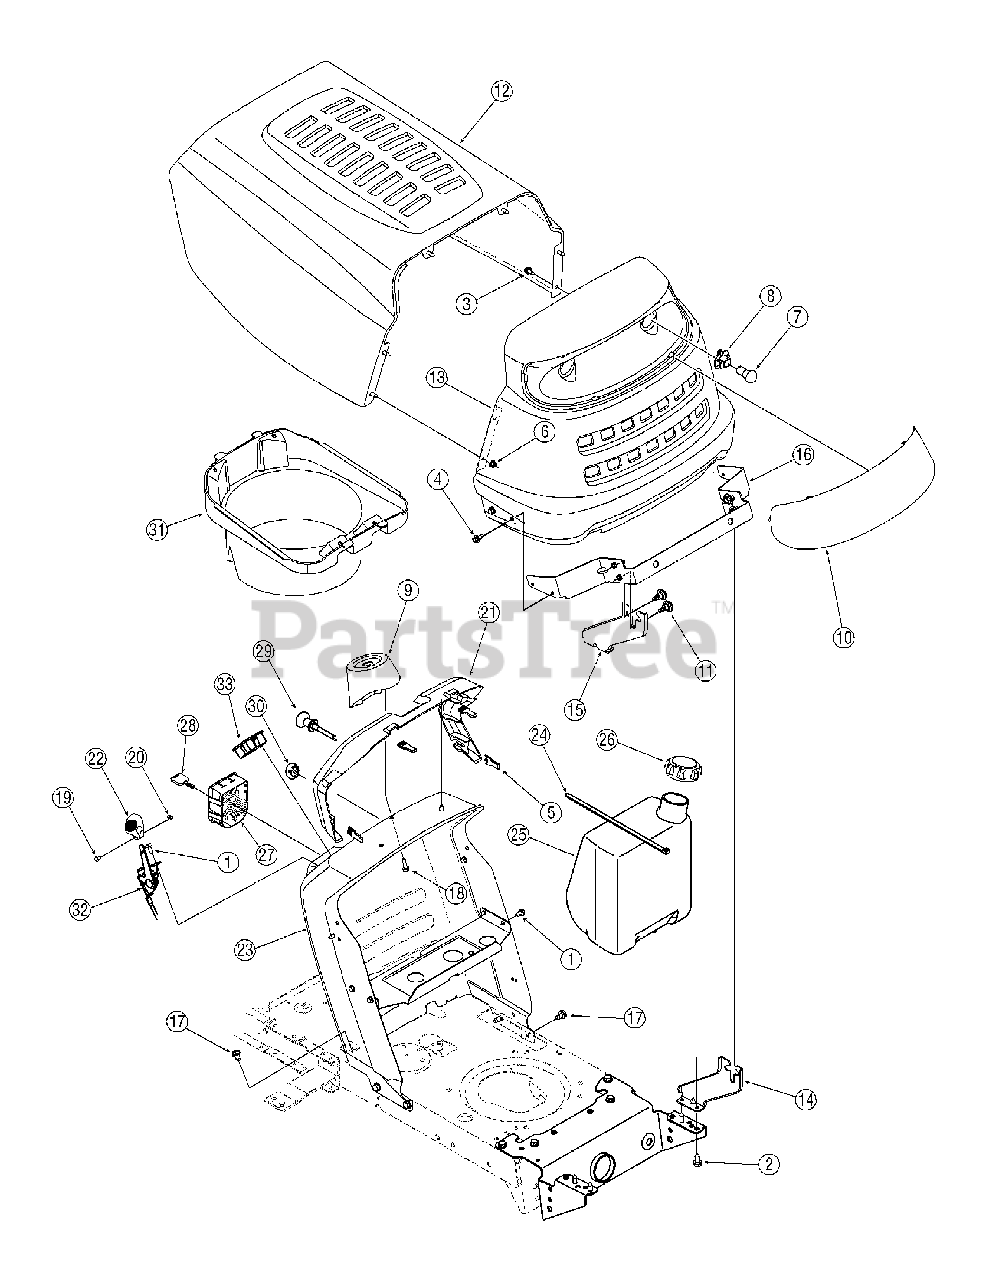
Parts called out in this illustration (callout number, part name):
1	Screw, 1/4-20, 0.500
2	Screw, 5/16-12, 0.750
3	Screw, 1/4-20, .620, Gr5
4	Screw, 1/4-20, .625
5	Nut, 1/4-20, Speed U-type
6	Nut, Flange Lock, 1/4-20, GrF, Nylon
7	Headlamp, 12V
8	Headlamp Socket
9	Collar, Dash
11	Screw, Shoulder, .43 x.29, 5/16-18
15	Pivot Bracket, RH
16	Pivot Bracket, Grille
17	Screw, 5/16-18, 0.500
18	Screw, 1/4-15, 0.750
19	Screw, Machine, #8-32, 0.375
20	Nut, Hex, #8-32, GrA
21	Support, Steering
22	Knob, Control
23	Dash Assembly (Models w/o Ammeter)
25	Fuel Tank, 1.5 gal.
26	Fuel Tank Cap
27	Module, Ignition Switch
29	Choke Control, 37.5"
31	Plenum (Single Cylinder Engine)
31	Plenum (Twin Cylinder Engine)
32	Throttle/Choke Control, 25" (Single Cylinder Engine)
32	Throttle Control, 39" (Twin Cylinder Engine)
33	Ammeter
